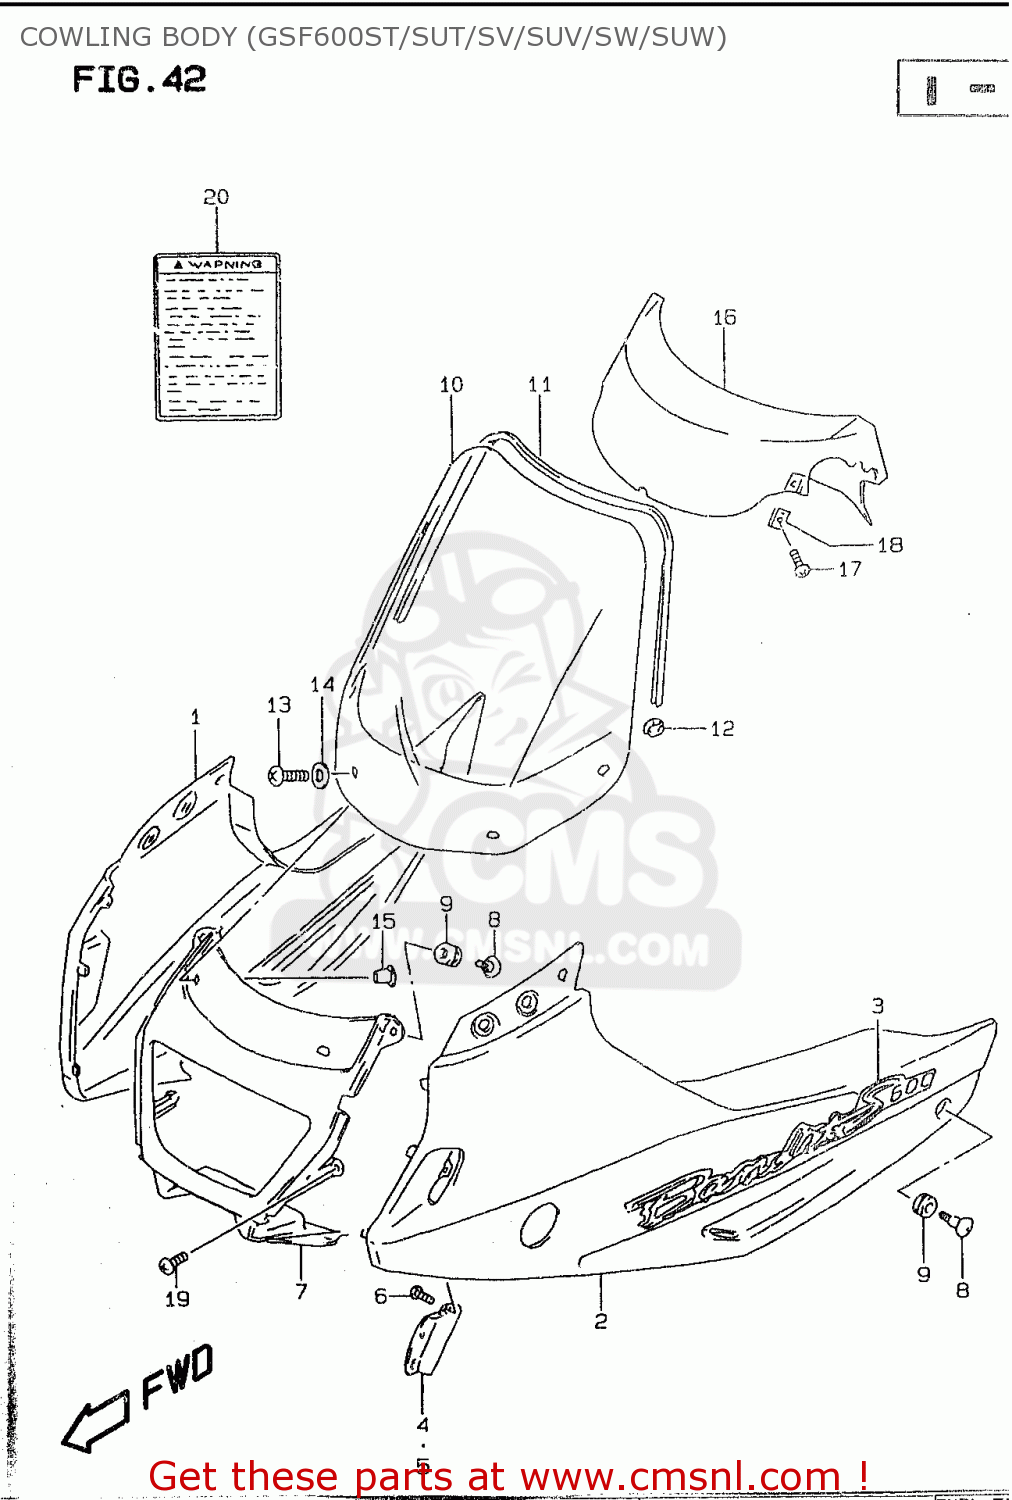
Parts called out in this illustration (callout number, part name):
1	COWLING ASSY,SIDE,R
2	COWLING ASSY,SIDE,L
3	EMBLEM,COWLING SIDE
4	COVER,COWLING INNER,R
5	COVER,COWLING INNER,L
6	SCREW 5X10
7	COWLING ASSY,CTR
8	SCREW(6X20)
9	CUSHION
10	WINDSCREEN SET
11	MOLDING WINDSCREEN
12	CLIP,WINDSCREEN MOLDING
13	SCREW(5X14)
14	WASHER
15	NUT
16	PANEL,INNER
17	SCREW L:12
18	NUT
19	SCREW
20	LABEL (WARNING SCREEN)
